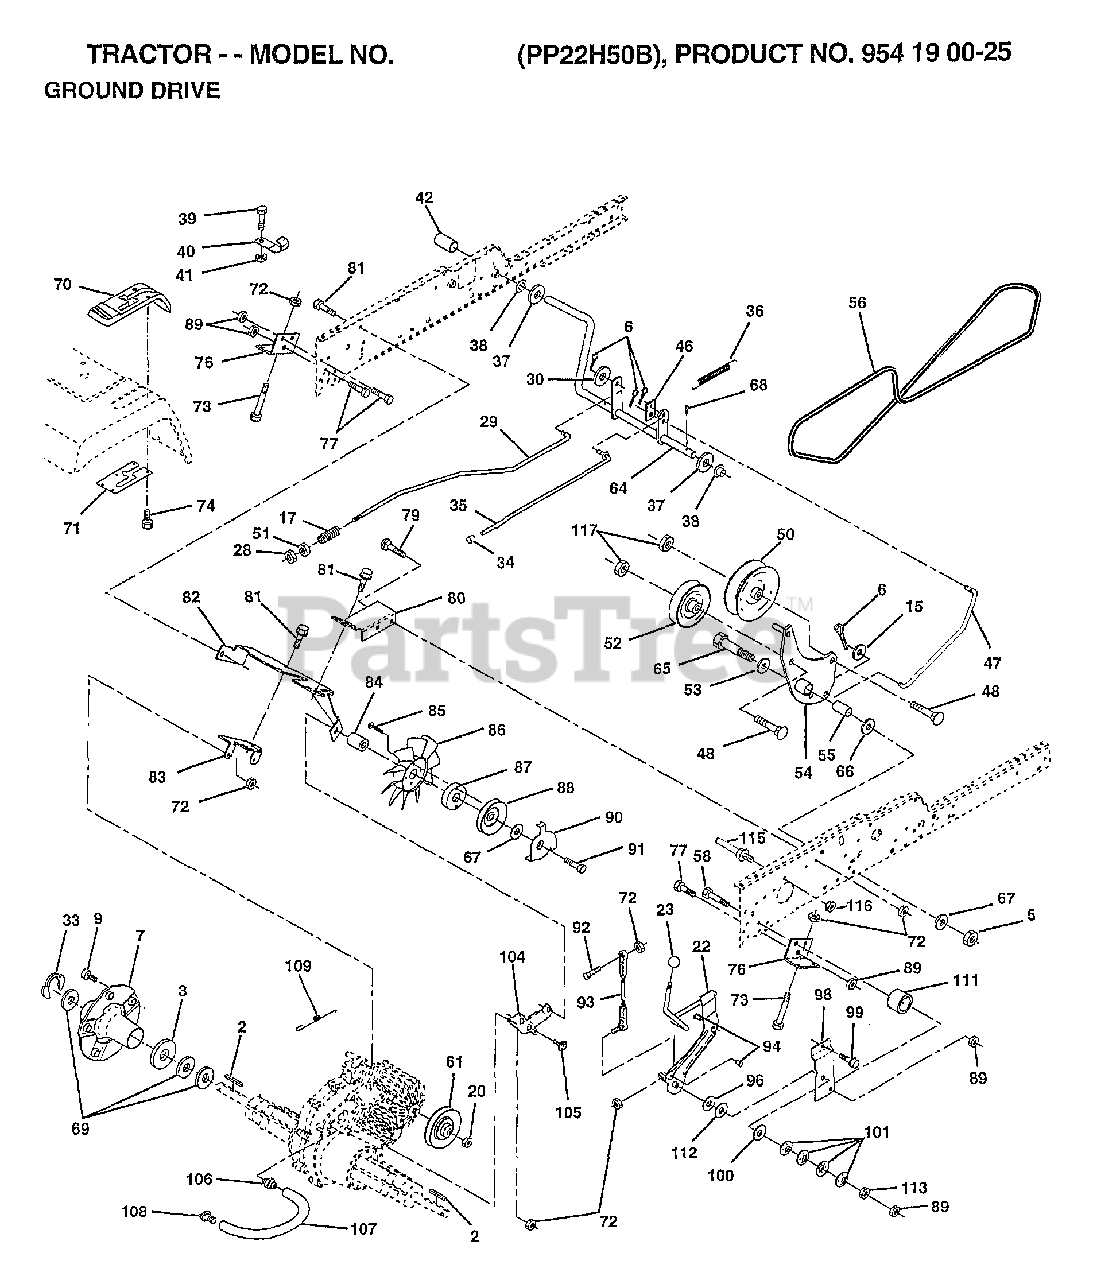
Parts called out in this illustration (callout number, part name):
2	KEY 1/4 X 2.5
3	WASHER T
6	COTTER PIN
7	HUB WHEEL ASM
9	BOLT.HUB.WHL.REAR
15	WASHER
17	SPRING ROD BRAKE
22	ARM ASM SHIFT
23	KNOB.DUCKHEAD.1/2
28	NUT
29	ROD BRAKE
30	WASHER HYT
33	E RING HYT
34	PLUNGER CAP T
35	ROD BRAKE PART GT
36	SPRING.GRND.DRIVE
37	WASHER
38	BUSHING.NYLINER
39	SCREW
40	ACT-SWITCH T
42	"COVER,PEDAL"
46	RETAINER.SPRING
47	ROD.CLUTCH
48	BOLT.3/8-16X1.50
50	FLAT IDLER PULLEY
52	PULLEY.IDLER.V.GR
53	WASHER T
54	CLUTCH.ARM.ASM
55	"LY, BEARING"
56	BELT-V 84.5
58	BOLT
61	PULLEY TRANSAXLE
64	SHAFT-BRAKE/CLUTC
65	AXLE BOLT
66	WASHER.HARD.BLADE
67	WASHER
68	ROLL PIN STD
69	WASHER
71	"PLATE CONSOLE,SFT"
72	NUT
73	BOLT.HEX.FLGHD.
74	SCREW HEXWSH H-L
76	BRACKET TRAN VGTH
77	BOLT
79	BOLT
80	BRACKET TORQUE RH
81	SCREW
82	BRACKET.MTG.FAN
83	STRAP TORQUE MID
84	SPACER
85	SCREW YTV
86	"FAN 7"" HYDRO"
87	ADAPTER FAN
88	PULLEY FAN
89	NUT GTV
90	KEEPER BELT
91	SCREW.HXWSH.3/8
93	LINK ASM SHIFT
94	XMAS TREE FASTNER
96	WASHER NICKEL PLT
98	BRACKET SHIFT
99	SCREW LT
100	WASHER COMPRESSIN
101	WASHER-BELLVILLE
104	BRACKET IDLER
105	SCREW CRT
106	O-RING.ASM.70110
107	"LINE FUEL,HYD 15"""
108	CAP.VENT.70109
109	SPRING BRAKE
111	"SPACER-LEVER,SHIF"
112	"WASHER-NYLON,HIGH"
113	NUT
115	"KEEPER,DRIVE BELT"
116	"NUT HEX,LOCK,FLAN"
